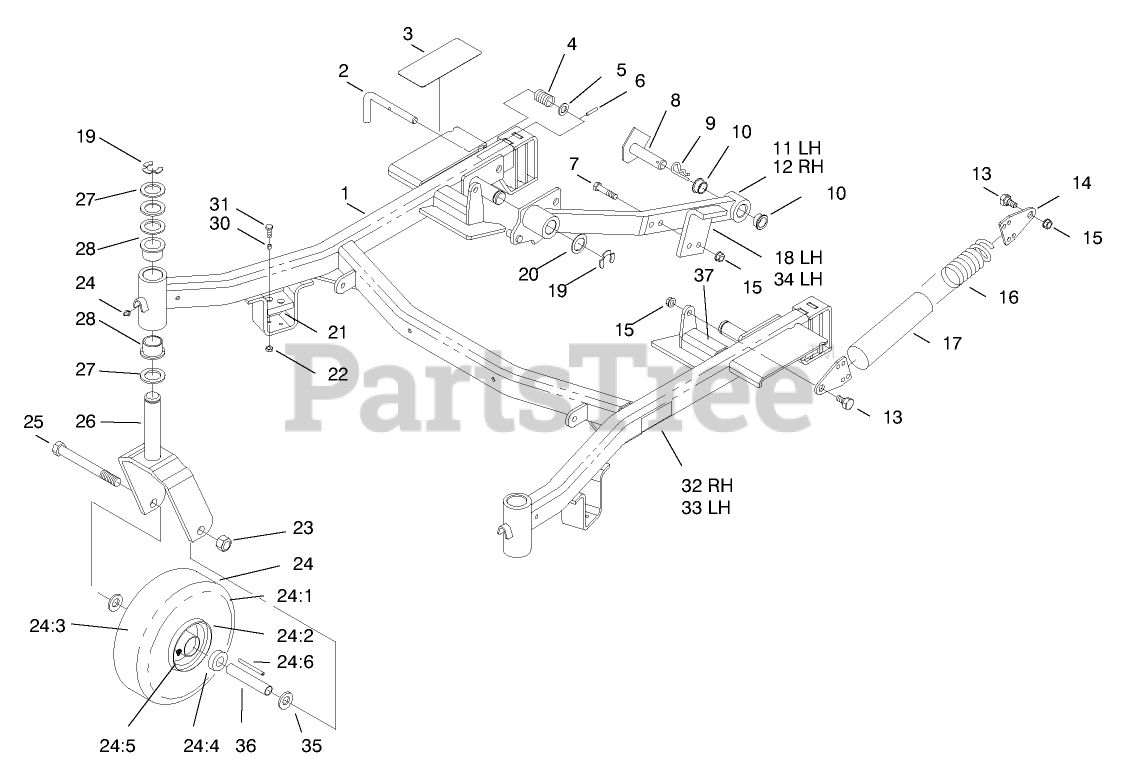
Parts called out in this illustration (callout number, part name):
1	FRAME-CARRIER
2	PIN - PIVOT
3	PAD - ABRASIVE,FOOTSTEP
4	SPRING - COMPRESSION
5	WASHER-THRUST
6	PIN-SPRING
7	SCREW-HH
8	PIVOT PIN ASM
9	PIN-HAIR
10	BEARING-FLANGE
11	Push Arm RH
12	Push Arm LH
13	BOLT-SHOULDER
14	PLATE-END, SPRING
15	NUT-LOCK, NI
16	SPRING-EXTENSION
17	COVER-SPRING
18	Stop-Pusharm
19	RING-RETAINING
20	Washer
21	CUSHION-RUBBER
22	NUT-LOCK, NI
23	NUT-HEX
24	WHEEL/TIRE ASM
24:2	Rim/Hub ASM
24:3	TUBE- W/VALVE
24:4	BEARING-OUTSIDE
24:5	FITTING-GREASE, 90 DEG
24:6	BEARING
25	SCREW-HH
26	FORK-CASTOR
27	WASHER-THRUST
28	BUSHING
29	FITTING-GREASE
30	SPACER
31	SCREW-HH
32	DECAL-HOC, RIGHT
33	DECAL-HOC, LEFT
34	STOP - PUSH ARM,RH R
35	WASHER-FLAT
36	SPANNER
37	DECAL-WARNING
